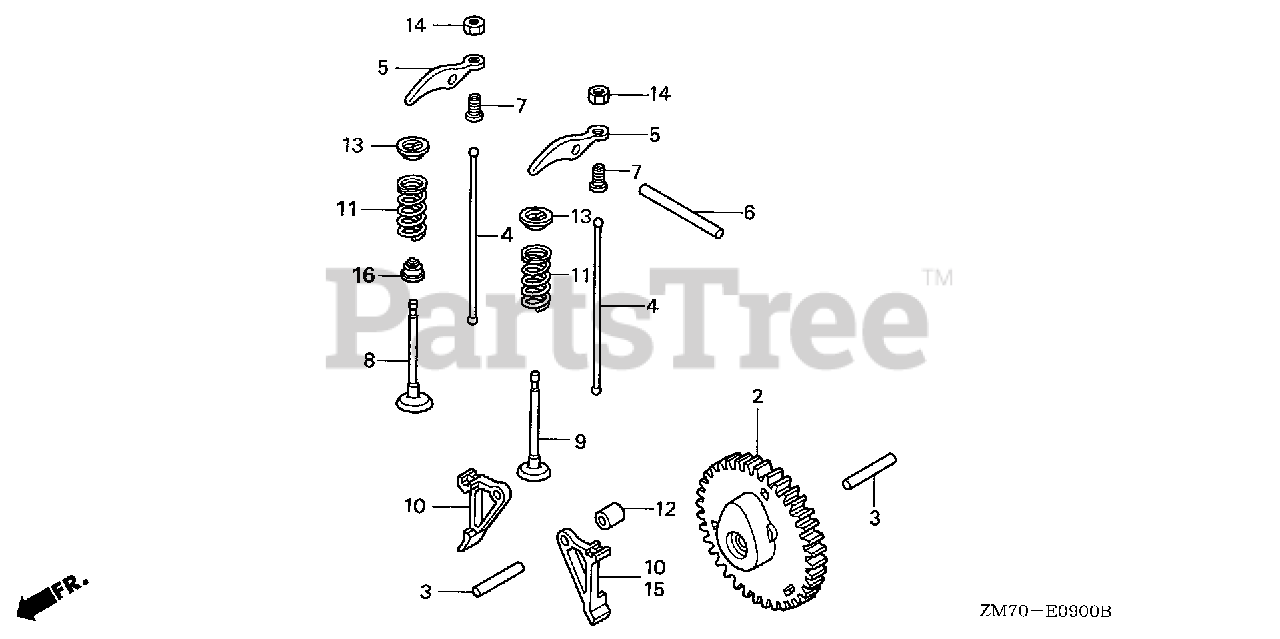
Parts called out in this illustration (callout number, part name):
2	CAMSHAFT ASSY.
3	ROLLER (5X29.8)
5	ARM, VALVE ROCKER
6	ROLLER (4X37.8)
7	PIVOT, ROCKER ARM
8	VALVE, IN.
9	VALVE, EX.
10	LIFTER, VALVE
11	SPRING, VALVE
12	COLLAR, LIFTER
13	RETAINER, VALVE SPRING
14	NUT, TAPPET ADJUSTING
15	LIFTER, EX. VALVE
